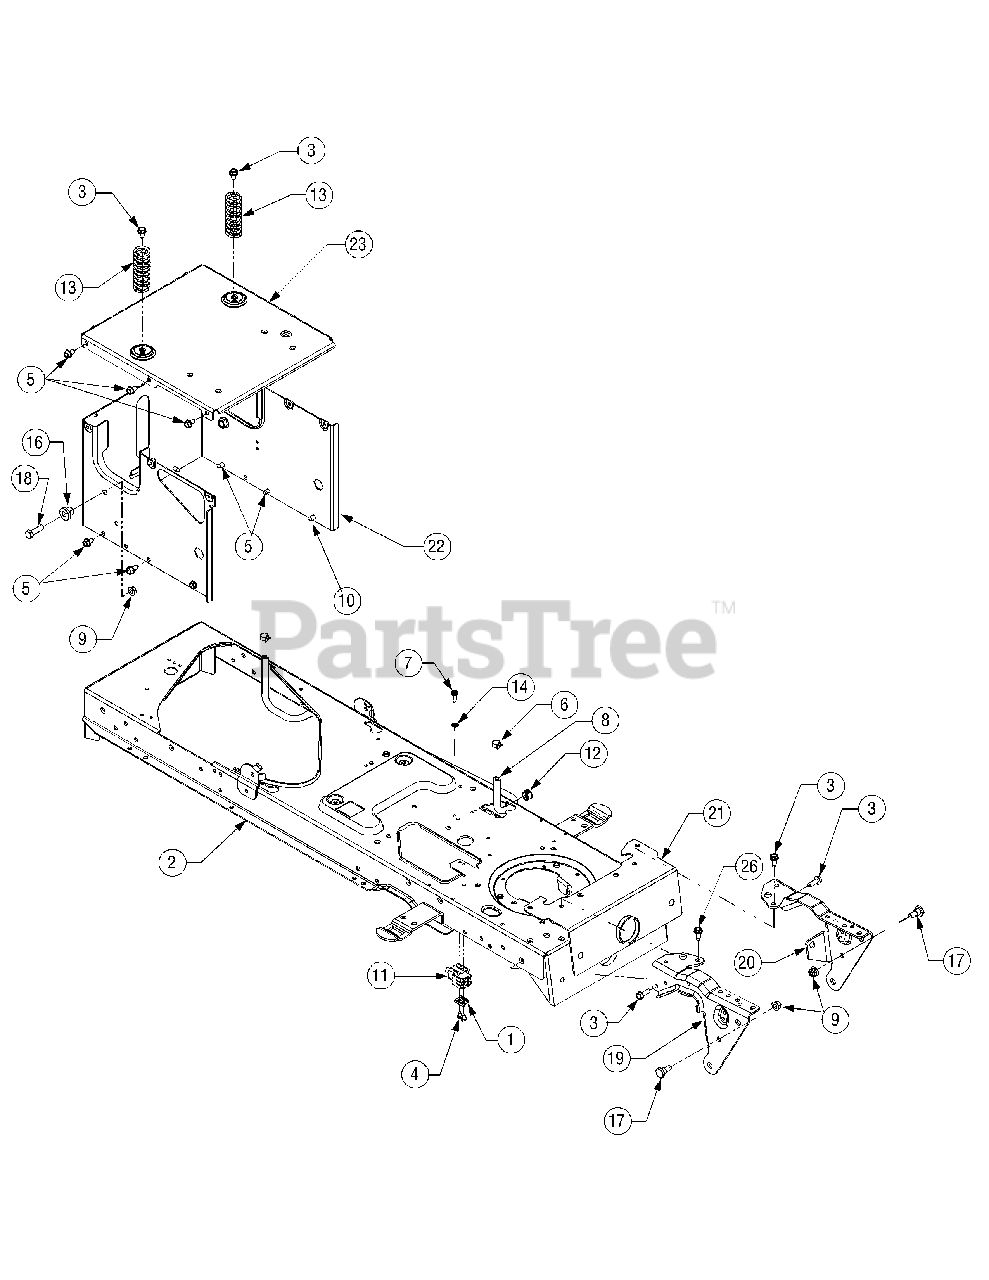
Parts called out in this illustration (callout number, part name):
1	Plate, Switch
4	Screw, Hex Wash. Hd. Tapp, 10-16 x .5
5	Screw, Self-tapping, 5/16-18, 0.75
6	Clamp, Hose, .490 Dia.
7	Screw, Hex Wash. 1/4-20 x 0.625
8	Fuel Line, Low Permeation, 29"
9	Nut, Nylon Lock, 3/8-16
10	Screw, Hex Wash. Tapp, 5/16-18 x .5
11	Switch, Interlock
12	Snap Bushing
13	Spring, Compression, 1.28 OD x 3.125
14	Washer, Lock, Ext 1/4
16	Shoulder Spacer
17	Shoulder Screw, 3/8-16
18	Hex Screw 3/8-16 x 1.25
